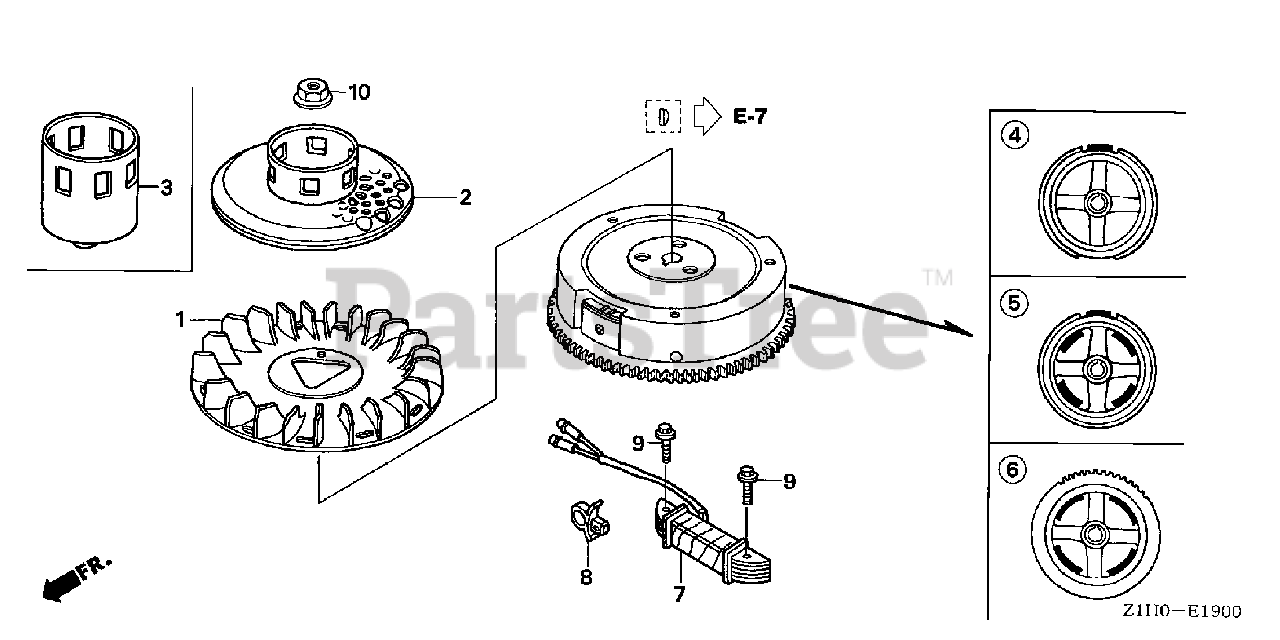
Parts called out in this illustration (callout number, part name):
1	FAN, COOLING
2	PULLEY, STARTER (SCREEN GRID)
10	NUT, SPECIAL (16MM)
